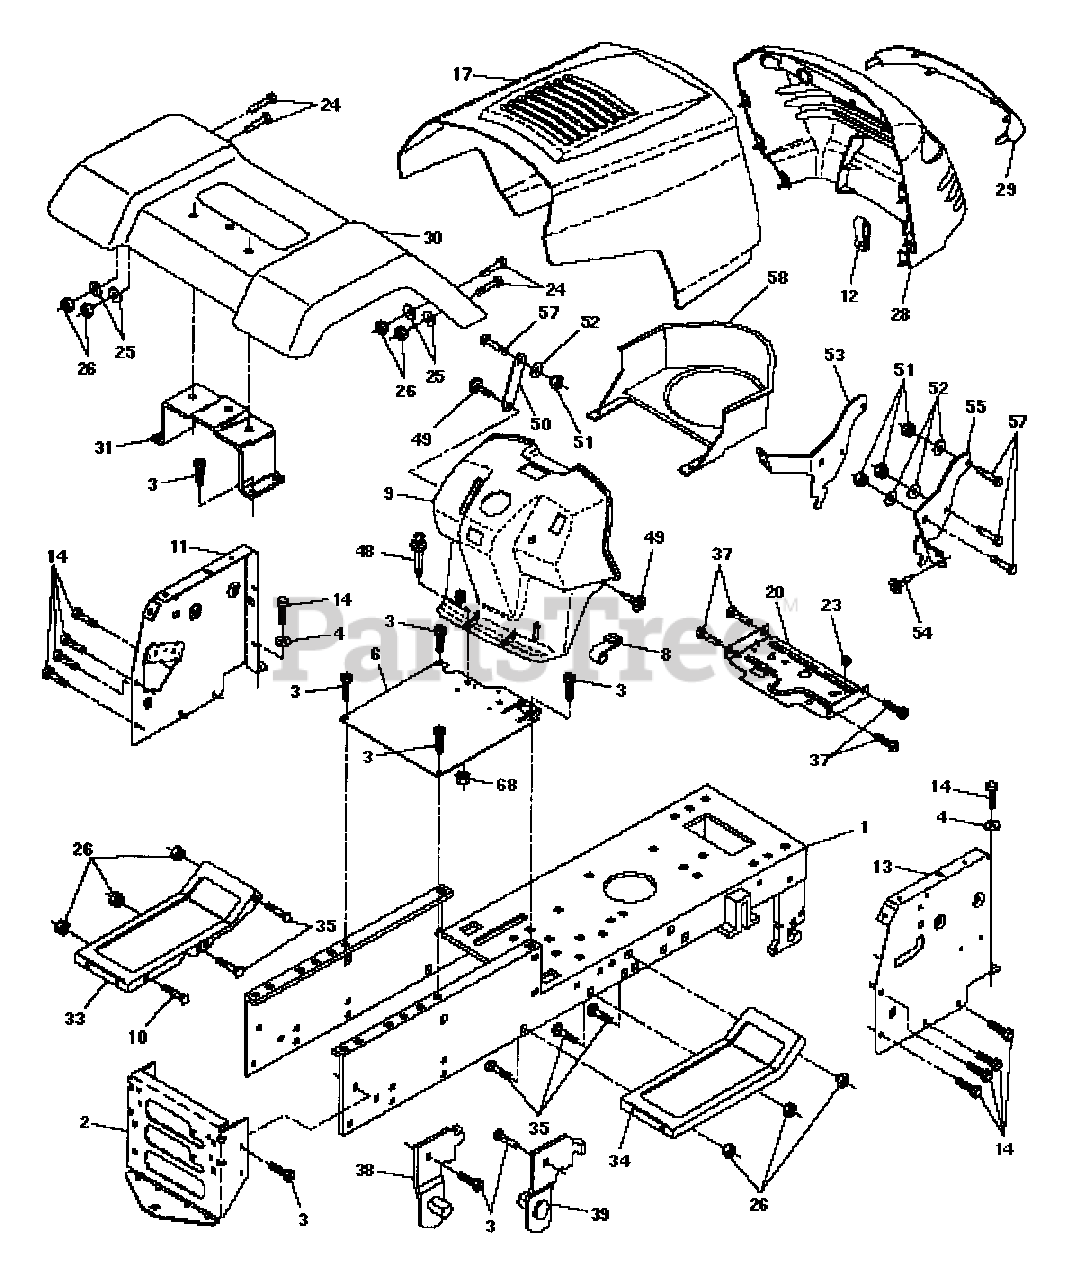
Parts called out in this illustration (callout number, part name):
1	Chassis Weldment 11ga
2	Drawbar, Stretch
3	Screw Thdrol 3/8-16x3/4 Ty-tt
4	Washer 13/32 x 3/4 x 16 Ga.
6	Saddle LT Fender Shift
8	Clip Insulator .406 Mtg Hole
9	Dash Private Label
10	Bolt Carriage 3/8-16 x 1
11	Panel Pnt Dash Lh
12	Clip Tinnerman Grille P/L
13	Panel Dash Rh Weldment
14	Screw Thdrol 3/8-16x1/2 Ty-tt
17	Hood Paint Steel Private Label
20	Plate Mtg Battery Fuel Tank
24	Bolt Fin Hex 3/8-16unc X 1 Gr. 5
25	Washer 13/32 X 13/16 X 12 Ga
26	Nut Lock Hex W/Ins 3/8-16 Unc
28	Grille Private Label
29	Lens Grille Private Label
30	Fender Pnt
31	Bracket Pnt Fender
33	Footrest Pnt Lh
34	Footrest Pnt Rh
35	Bolt Rdhd Sht Sqnk 3/8-16 X3/4
37	Screw Thdrol 5/16-18 X3/4
38	Bracket, Asm. Pivot, L.H., Mower Rear
39	Bracket, Asm. Pivot, R.H., Mower Rear
48	Rivet Push Plate D Plastick Blk
49	Screw Hexwsh. Thdrol 1/4-20 x 3/4
51	Nut Lock Hex W/Ins 1/4-20
52	Washer 9/32 x 7/8 x 16 Ga.
53	Bracket, Grille, LH
54	Screw Lock Spider #8 x 7/8
55	Bracket, Grille, RH
57	Bolt Hex 1/4-20 x 3/4
58	Air Duct P/L
68	Nut Keps Hex 1/4-20
